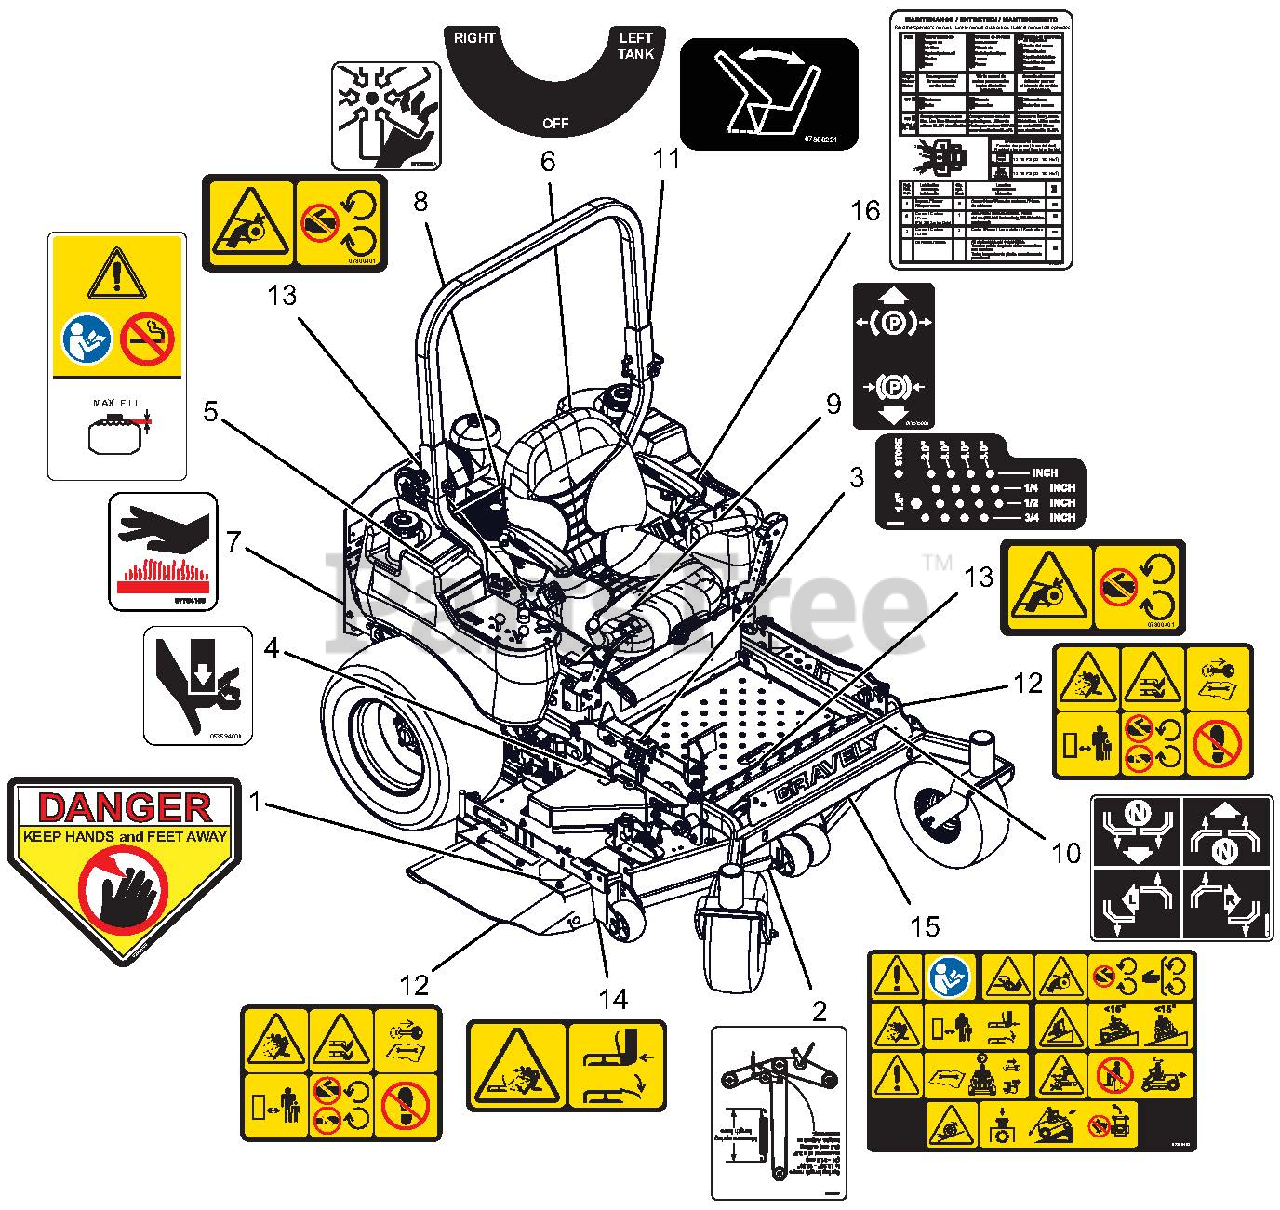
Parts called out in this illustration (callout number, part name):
1	DECAL, DANGER
2	DECAL, BELT ROUTING
3	DECAL, HEIGHT OF CUT
4	DECAL, PINCH POINT
5	DECAL, FUEL Warning
6	DECAL, FUEL CONTROL VALVE
7	DECAL HOT SURFACE
8	DECAL, DANGER - FAN
9	DECAL, PARKING BRAKE LEVER
10	DECAL, INSTRUCTIONAL - STEERING
11	DECAL, SEAT RELEASE
12	DECAL, SAFETY - MOWER DECK
13	DECAL, SAFETY - GUARDING
14	DECAL, SAFETY - DECK GUARDING
15	DECAL, MAIN SAFETY, COMMERCIAL
16	DECAL, MAINTENANCE
